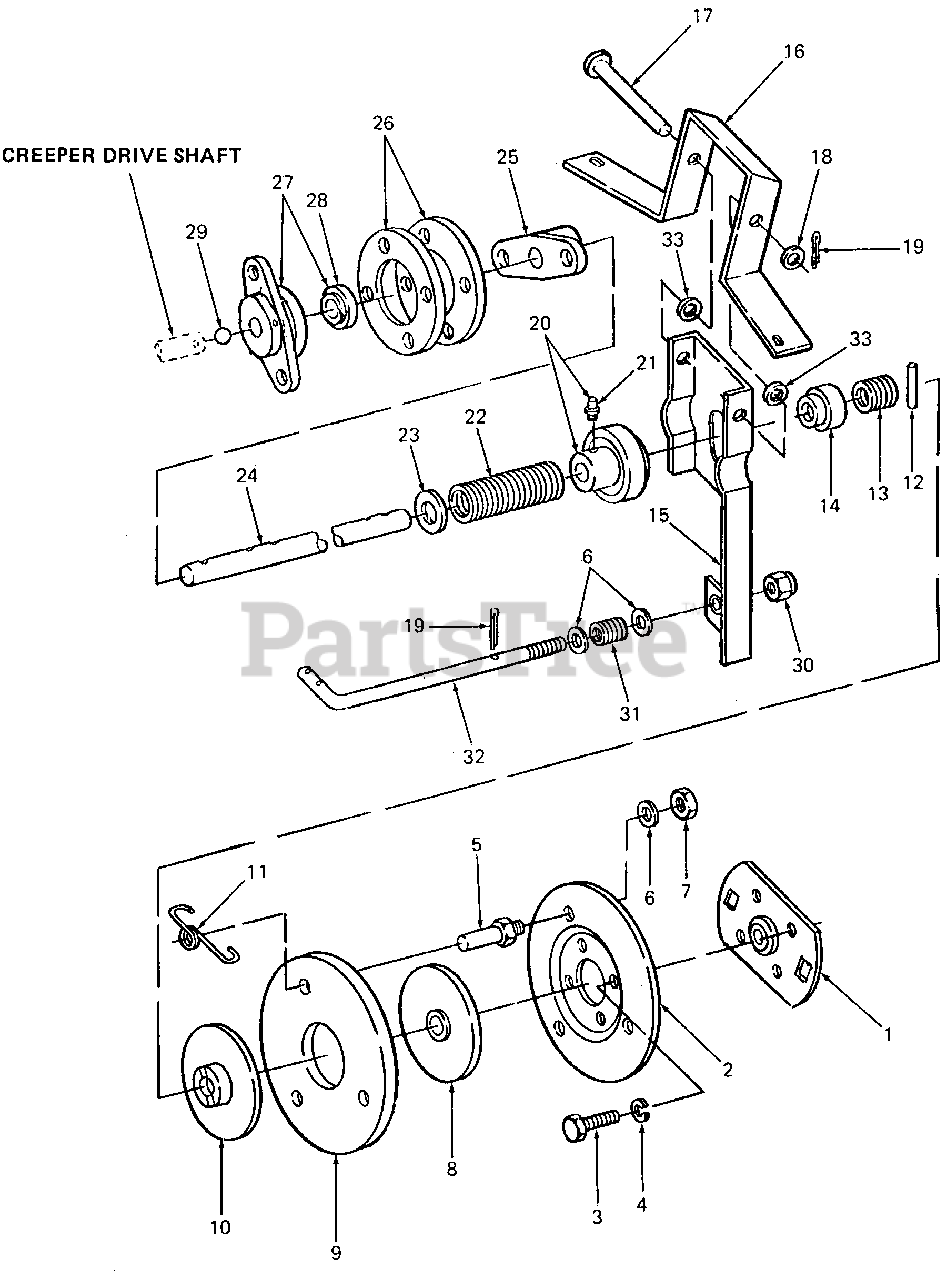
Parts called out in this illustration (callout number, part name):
1	Flange Assy, Drive Shaft
2	Disc, Clutch Driving
3	Screw, Hex Cap, 1/4-20 X .62 Lg GR5
4	Washer, Lock, 1/4
5	Stud, Drive
6	Washer, Flat, .406 X .75 X .063 Thk
7	Nut, Hex Jam, 3/8-16 GR5
8	Hub Assy, Pressure Plate Locating
9	Disc, Clutch Friction
10	Hub Assy, Pressure Plate
11	Spring, Driving Disc
12	Pin, Spiral Spring, 1/4 Dia X 1.50 Lg
13	Spring, Compression, .875 OD X .442 Lg
14	Spacer
16	Hanger, Clutch Lever
17	Pin, Clevis, .38 Dia X 3.69 Lg
18	Washer, Flat, .406 X .875 X .105 Thk
19	Pin, Cotter, 1/8 Dia X .75 Lg
20	Bearing Assy, Throwout
21	Fitting, Lube
22	Spring, Compression, 1.05 OD X 6.7 Lg
23	Washer, Flat, .635 X 1.0 X .120 Thk
24	Shaft, Drive
25	Arm, Coupling
26	Disc, Flexible Coupling
27	Coupler Assy
28	Bushing, Ball
29	Ball, Steel, 5/8 Dia, Chrome
30	Nut, Hex Insert Lock, 3/8-24 GR5
31	Spring, Compression, .50 OD X 3.75 Lg
32	Rod, Clutch Release
33	Washer, Flat, .406 X .75 X .063 Thk
